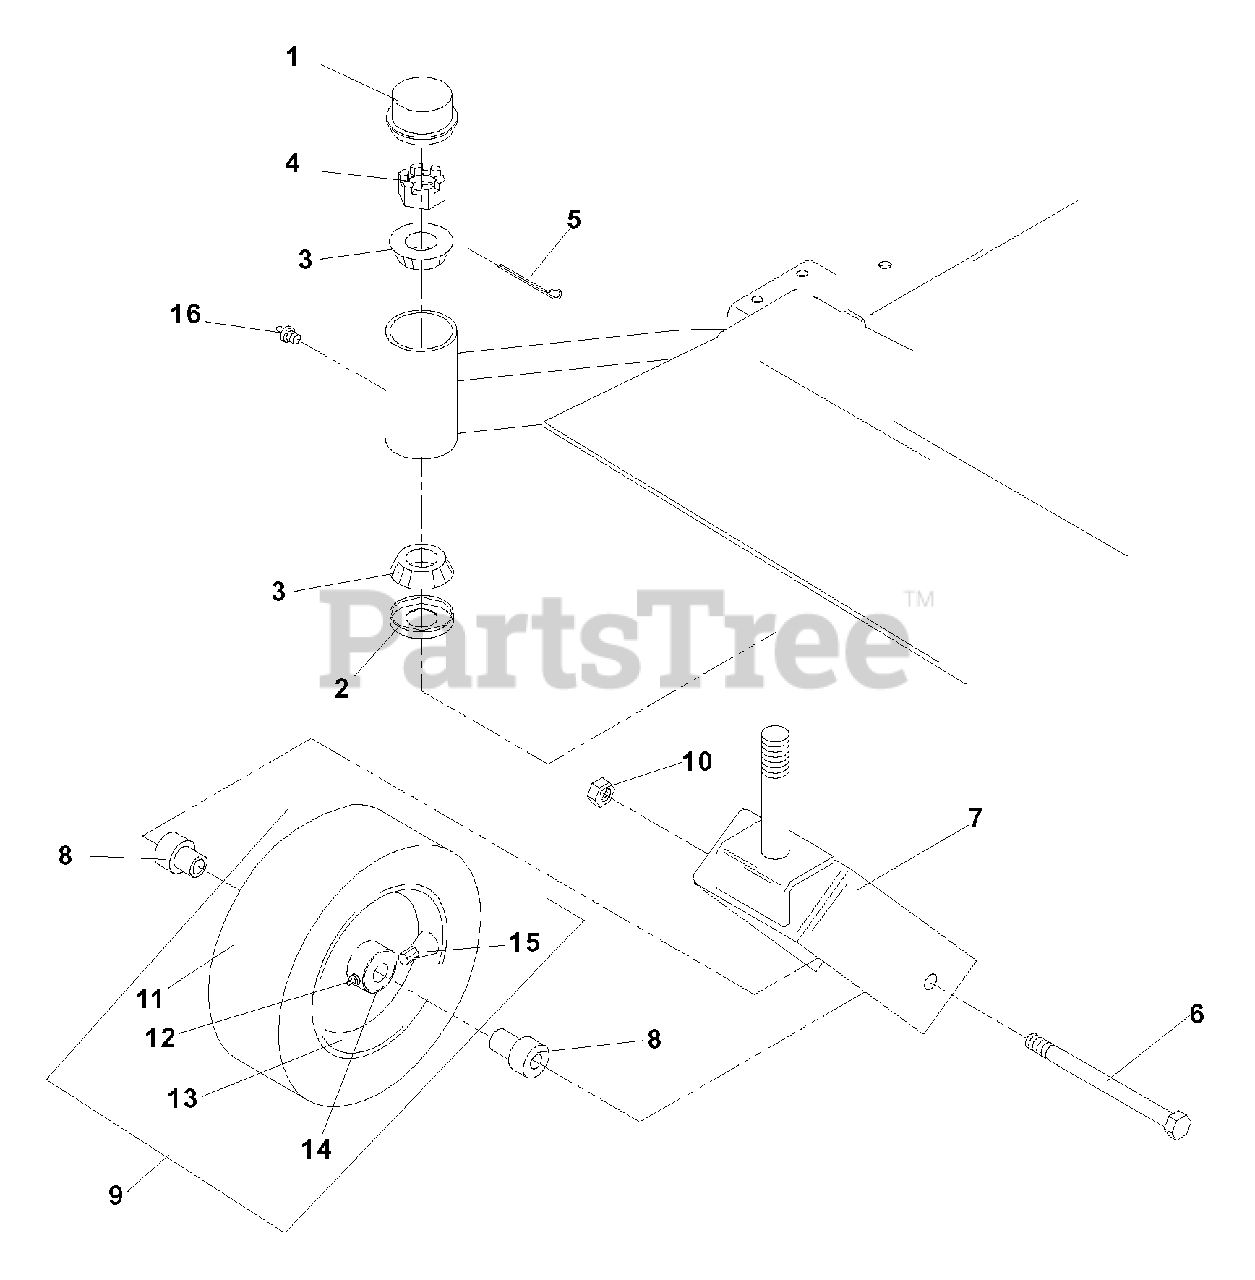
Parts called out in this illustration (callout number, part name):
1	CAP, GREASE
2	NUT, 1"C, CASTLE
3	PIN, COTTER, 1/8 x 2
6	HCS, 1/2 - 13 x 9 1/2,
7	YOKE, CASTER
8	SPACER, AXLE
9	TIRE & WHEEL, COMPLETE
10	NUT, 1/2C, NYLOC
12	ZERK
